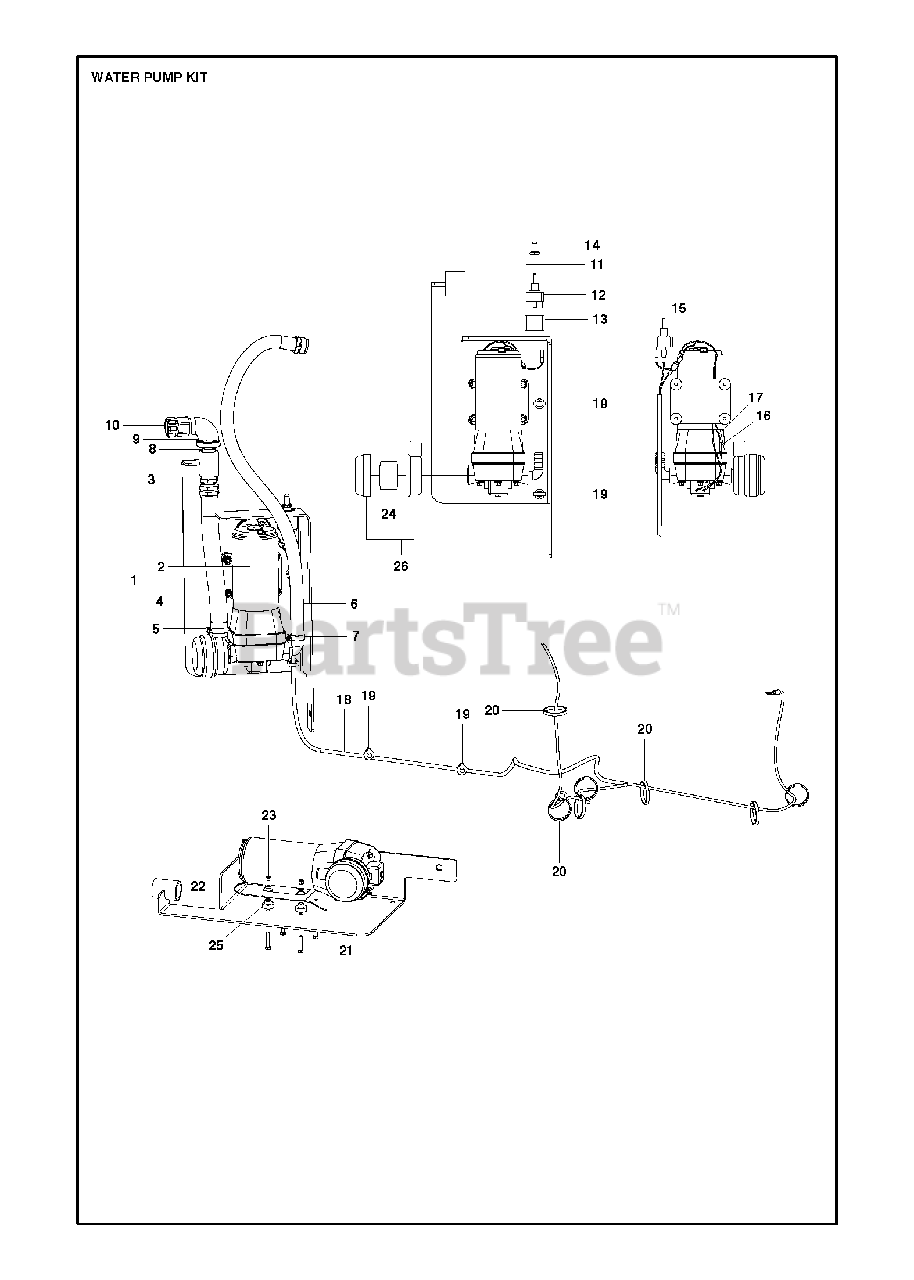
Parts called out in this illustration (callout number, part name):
15	TERM., MALE DISCONNECT, 1/4"
22	WASHER
23	HEXAGON LOCKING NUT
24	STRAINER SCREEN. W/P INLET FILTER
